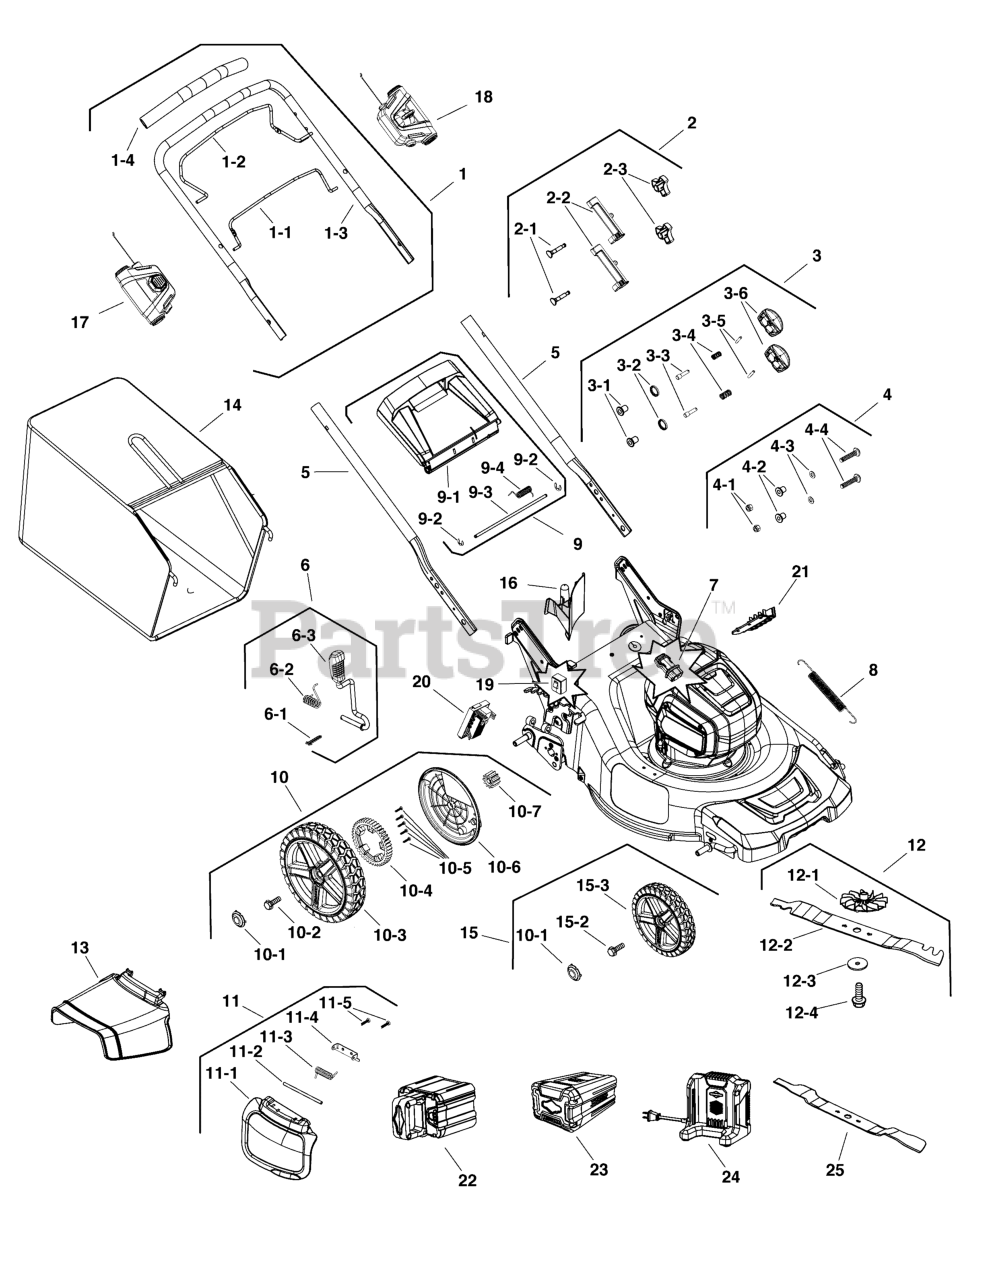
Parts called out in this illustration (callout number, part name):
1	KIT, Upper Handle
1-1	BAIL ASSEMBLY
1-2	LEVER, Self-Propelled
1-3	HANDLE, Upper
1-4	GRIP, foam
2	KIT, Mounting Hardware
2-1	BOLT
2-2	SLEEVE
3	KIT, Knob, Lower Handle
3-1	INSERT
3-2	GASKET
3-3	POST
3-4	SPRING
3-5	PIN
3-6	KNOB, Handle
4	KIT, Hardware, Lower Handle
4-2	INSERT
4-3	WASHER, Flat
4-4	BOLT
5	KIT, Lower Handle
6	KIT, Height Adjust
6-1	PIN, Cotter
6-2	SPRING
6-3	HANDLE, Height Adjust
7	KEY, Safety
8	SPRING, Tension, Lift
9	KIT, Rear Cover
9-1	COVER, Rear
9-2	WASHER, Split
9-3	ROD, Rear Cover
9-4	SPRING
10	KIT, Rear Wheel, 10"
10-4	GEAR, Drive
10-6	COVER, Dust
10-7	GEAR, Drive
11	KIT, Cover, Side Discharge
11-1	COVER, Side Discharge
11-2	ROD, Side Discharge
11-3	SPRING, Torsion
11-4	BRACKET
12	KIT, Mower Blade, 20"
12-3	WASHER
12-4	BOLT, Flange
13	DEFLECTOR, Side Discharge
14	GRASS CATCHER ASSEMBLY
15	KIT, Front Wheel, 8"
16	PLUG, Mulching
17	CONTROL PANEL ASSEMBLY
18	SPEED CONTROL ASSEMBLY
19	SWITCH, Safety
20	BOARD, Circuit
21	TERMINAL, Battery
22	* BATTERY, 2.0, 48V
23	* BATTERY, 5.0, 48V
24	* BATTERY CHARGER, 48V
25	MOWER BLADE, Mulching
